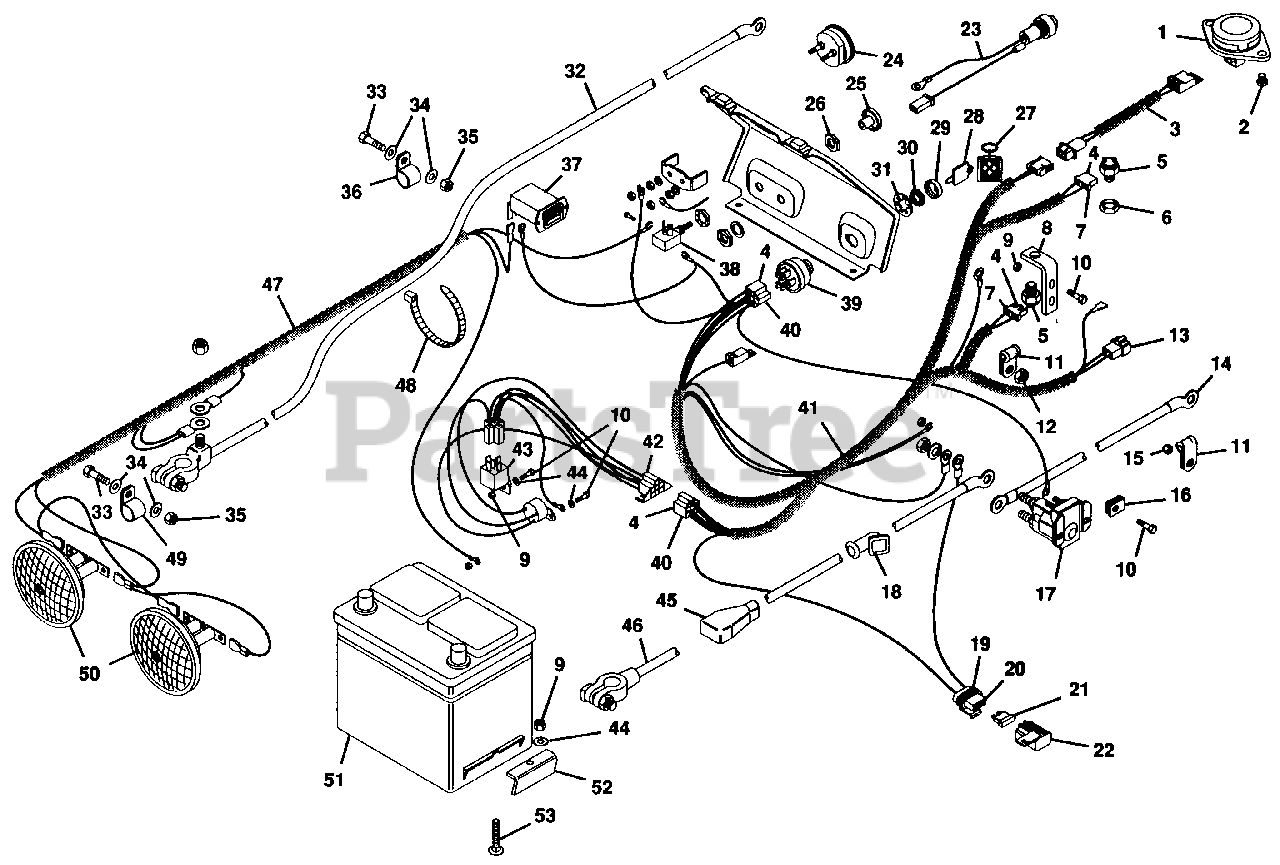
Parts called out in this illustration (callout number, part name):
1	SWITCH, SEAT
2	SCREW, MACHINE 1/4-20
3	HARNESS, WIRING SEAT SWITCH
4	TERMINAL
5	SWITCH, INTERLOCK
6	NUT, STAMPED 9/16-18
7	CONNECTOR, 2-WIRE SWITCH
8	BRACKET, SWITCH
9	NUT, LOCK 1/4-20
10	BOLT, HEX 1/4-20X.75
11	CLAMP
12	NUT, LOCK 3/8-16
13	CONNECTOR
14	CABLE, STARTER
15	NUT, LOCK 3/8-16
16	NUT, SPEED 1/4-20
17	SWITCH, MAGNETIC
18	BOOT, BATTERY CABLE
19	CONNECTOR
20	TERMINAL, 14-16 GAUGE
21	FUSE, 25 AMP
22	COVER
23	LIGHT, INDICATOR
24	GAUGE, AMMETER
25	KNOB, LIGHT SWITCH
26	NUT, SPECIAL LIGHT SWITCH
27	CHAIN, KEY
28	KEY, IGNITION SWITCH
29	BOOT, 9/16 SWITCH
30	NUT, JAM 9/16-24
31	WASHER, LOCK 9/16 INT. TOOTH
32	CABLE, NEGATIVE BATTERY
33	BOLT, HEX 5/16-18X1.00
34	WASHER, FLAT .344X.688X.065
35	NUT, LOCK 5/16-18
36	CLAMP, NYLON
37	HOURMETER
38	SWITCH, LIGHT
39	SWITCH, IGNITION
40	CONNECTOR
41	HARNESS, WIRING
42	MODULE, TIME DELAY
43	RELAY
44	WASHER, FLAT .281X.625X.065
45	COVER, BATTERY TERMINAL
46	CABLE, BATTERY TO MAGNETIC SWITCH
47	HARNESS, WIRING GROUND AND LIGHT
48	TIE, CABLE
49	CLAMP, NYLON
50	HEADLIGHT
51	BATTERY, 12 VOLT
52	CLAMP
53	BOLT, 1/4-20X1.75 RD HD SQ NK
